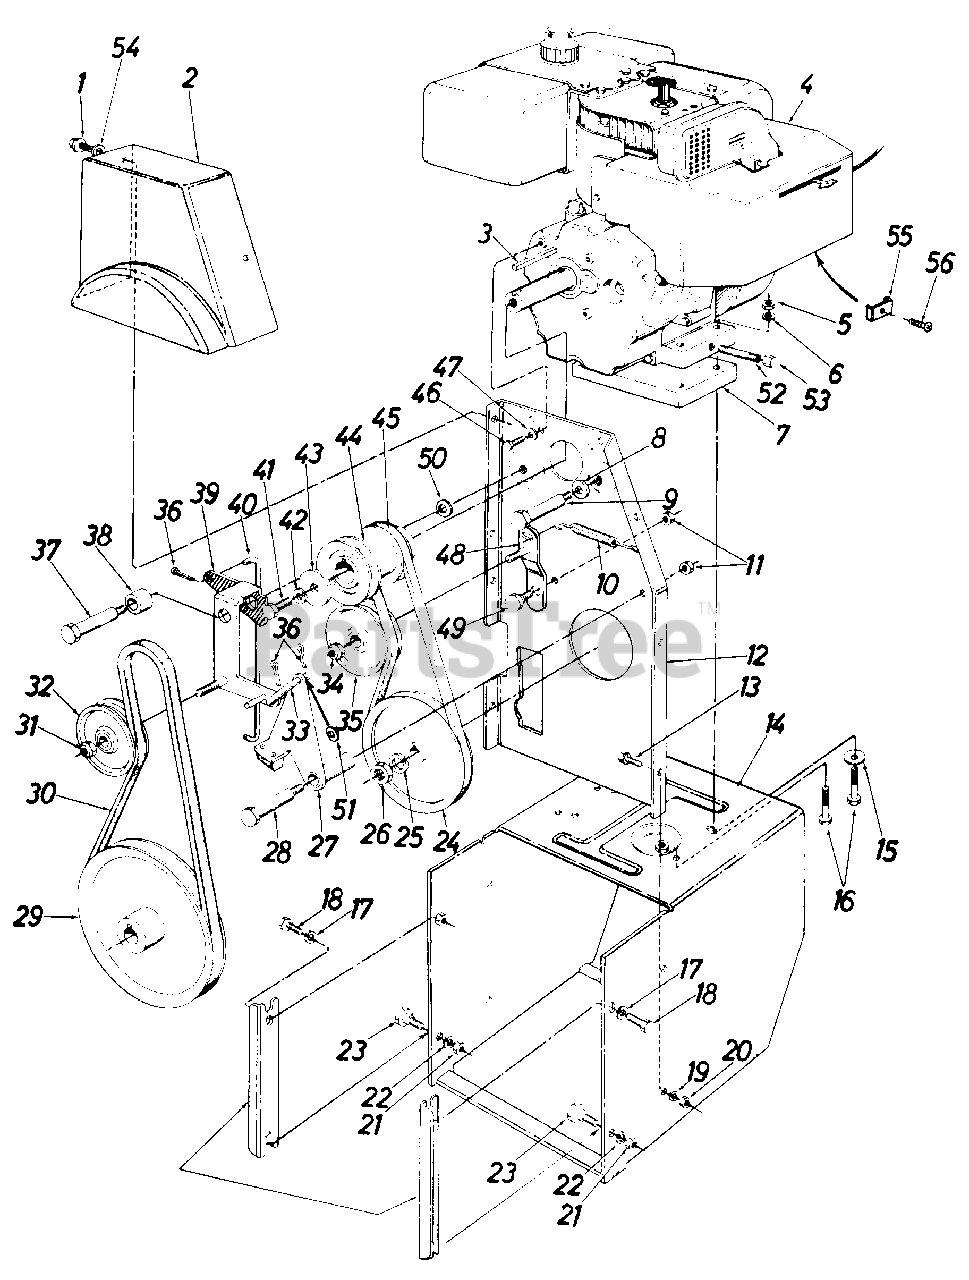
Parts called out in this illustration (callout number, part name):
1	Hex Wash. Self-Tap Scr. 5/16-24 x .50 " Lg.
2	Belt Cover
3	Sq. Key 1/4" x 1.50" Lg.
4	Engine
5	Hex Nut 5/16-18 Thd.*
6	L-Wash. 5/16" Scr.*
7	Engine Spacer Ass'y
8	Bell-Wash. .40 I.D. x .88 O.D.
9	Shld. Scr. .498" Dia. x 3.00" Lg.
10	Ext Spring .38 O.D. x 3.18" Lg.
11	Hex Cent. L-Nut 3/8-16 Thd.
12	Engine Brkt. Ass'y.
13	Hex Sems Scr. 5/16-18 x .75" Lg.*
14	Frame Ass'y.
15	Fl-Wash. .345 0 I.D. x .75 O.D. x .060
16	Hex Scr. 5/16-18 x 2.50" Lg.*
17	L-Wash. 3/8" Scr. H.D.
18	Pilot Scr. 3/8-16 x .88" Lg.
19	L-Wash. 5/16" Scr.*
20	Hex Nut 5/16-18 Thd.*
21	Hex Nut 3/8-16 Thd.*
22	L-Wash. 3/8" Scr. H.D.
23	Shld. Scr. .498" Dia. x .340" Lg.
24	V-Pulley .628 I.D. x 7.50 O.D.
25	L-Wash. for 5/8" Scr.*
26	Hex Ins. Jam L-Nut 5/8-18 Thd.
27	Brake Brkt. Ass'y.
28	Shld. Scr. .498" Dia. x 2.00" Lg.
29	V-Pulley .875 0 I.D. x 10.12 O.D.
30	"V"-Belt 1/2" x 45.0" Lg.
31	Hex Ins. Jam L-Nut 3/8-24 Thd.
32	Fl-ldler w/ Flanges 3.0 O.D.
33	Brake Linkage Ass'y.
34	Hex Ins. Jam L-Nut 3/8-24 Thd.
35	3.0" O.D. Fl-ldler w/ Flanges
36	Int. Cot. Pin 5/16" Dia.
37	Shld. Scr. .625 Dia. x 2.750" Lg.
38	Spacer .75 O.D. x 1.00" Lg.
41	Hex Bolt 3/8-24 x 1.25" Lg.
42	L-Wash. 3/8" Scr. H.D.
44	Engine Pulley Double G roove
45	"V"-Belt 3/8 x 35.5 0 Lg.
46	Hex Scr. 5/16-24 x .62" Lg.*
47	Bell-Wash. .345 0 I.D. x .88 O.D. x .060
48	Drive Idler Brkt. Ass'y.
49	Shld. Scr. .625" Dia. x .170"
50	Bell-Wash. .40 I.D. x 1.12 O.D.
51	Fl-Wash. .34 I.D. x .750 O.D. x .05
52	Pipe Nipple 1/2" Pipe Thd. x 3.00" Lg.
53	Hex Scr. 1/4-18 Pipe Thd.
54	Fl-Wash. .340 I.D. x .62 O.D. x .62
55	Throttle Control Wire Clamp
56	Hex Sems Scr. #10-32 x .62" Lg.
